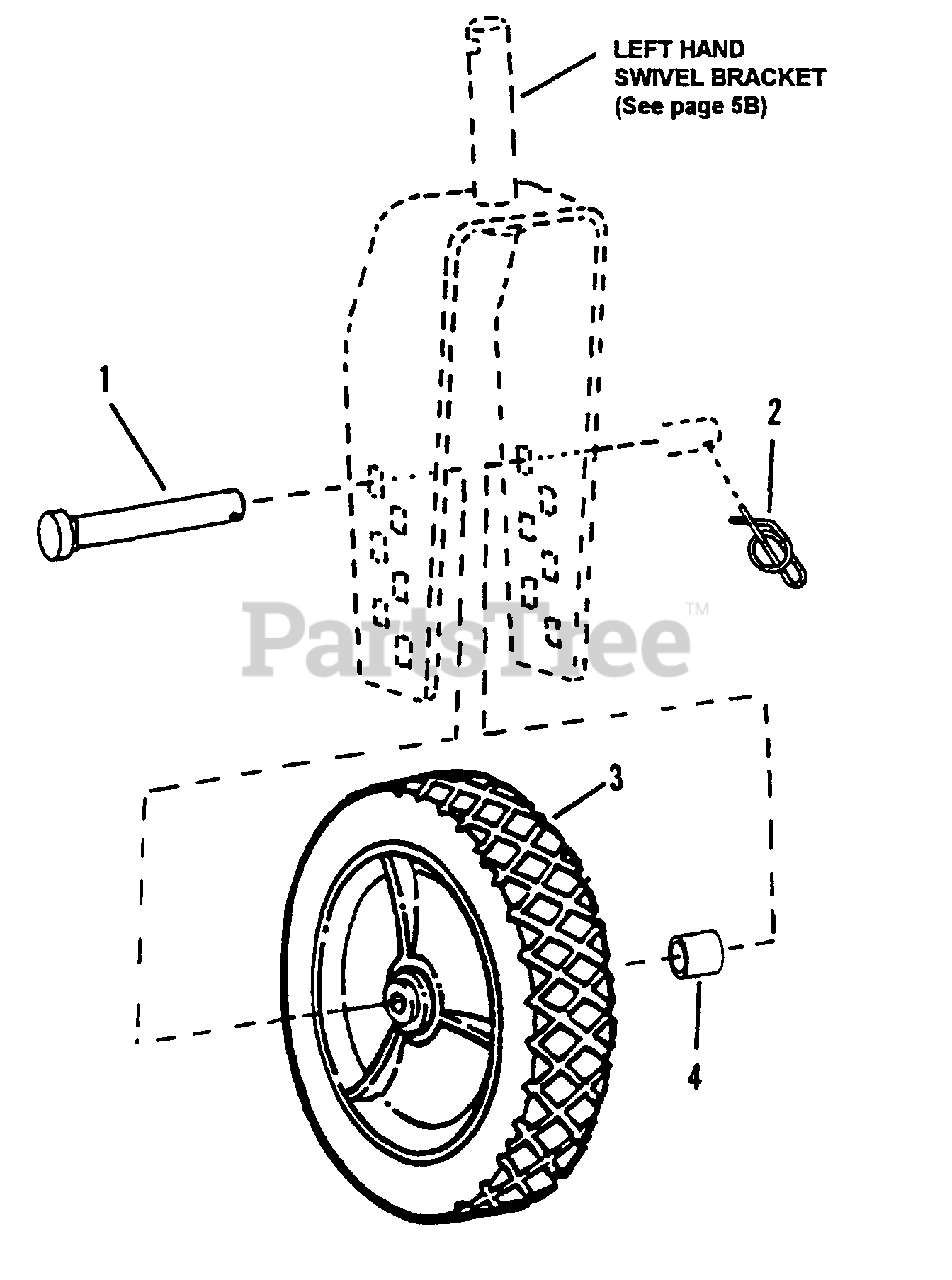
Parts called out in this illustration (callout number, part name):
1	PIN, Wheel
2	PIN, Swivel Wheel Lock
3	WHEEL, 8 x 1.75 Plastic
4	SPACER, Wheel
